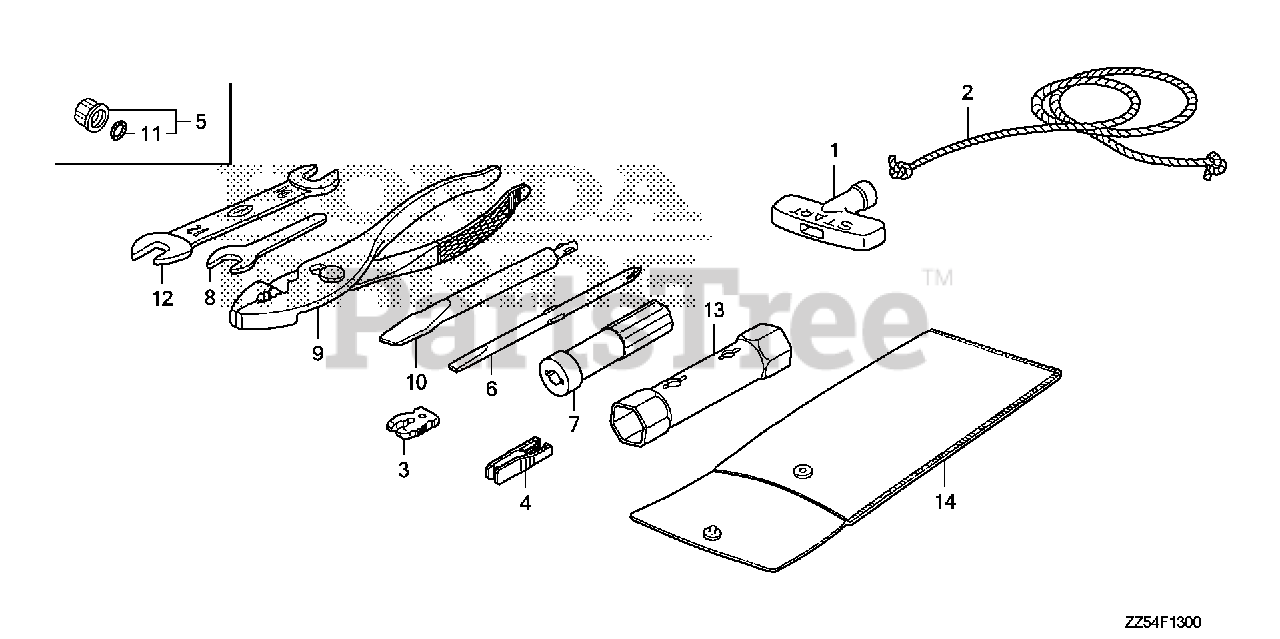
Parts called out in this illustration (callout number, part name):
1	KNOB, RECOIL STARTER
1	GRIP, STARTER
2	ROPE, RECOIL STARTER (1300MM)
3	CLIP, EMERGENCY LOCK
4	PULLER, MINI FUSE (SUMITOMO)
6	SCREWDRIVER (NO.2 PHILLIPS -)
8	WRENCH (8MM) (OPEN END) (NOT AVAILABLE)
9	PLIERS (135) (RIKEN)
10	SCREWDRIVER, CHECK BOLT
12	WRENCH (10X12) (OPEN END)
13	WRENCH, BOX (P18X19)
14	BAG, TOOL
